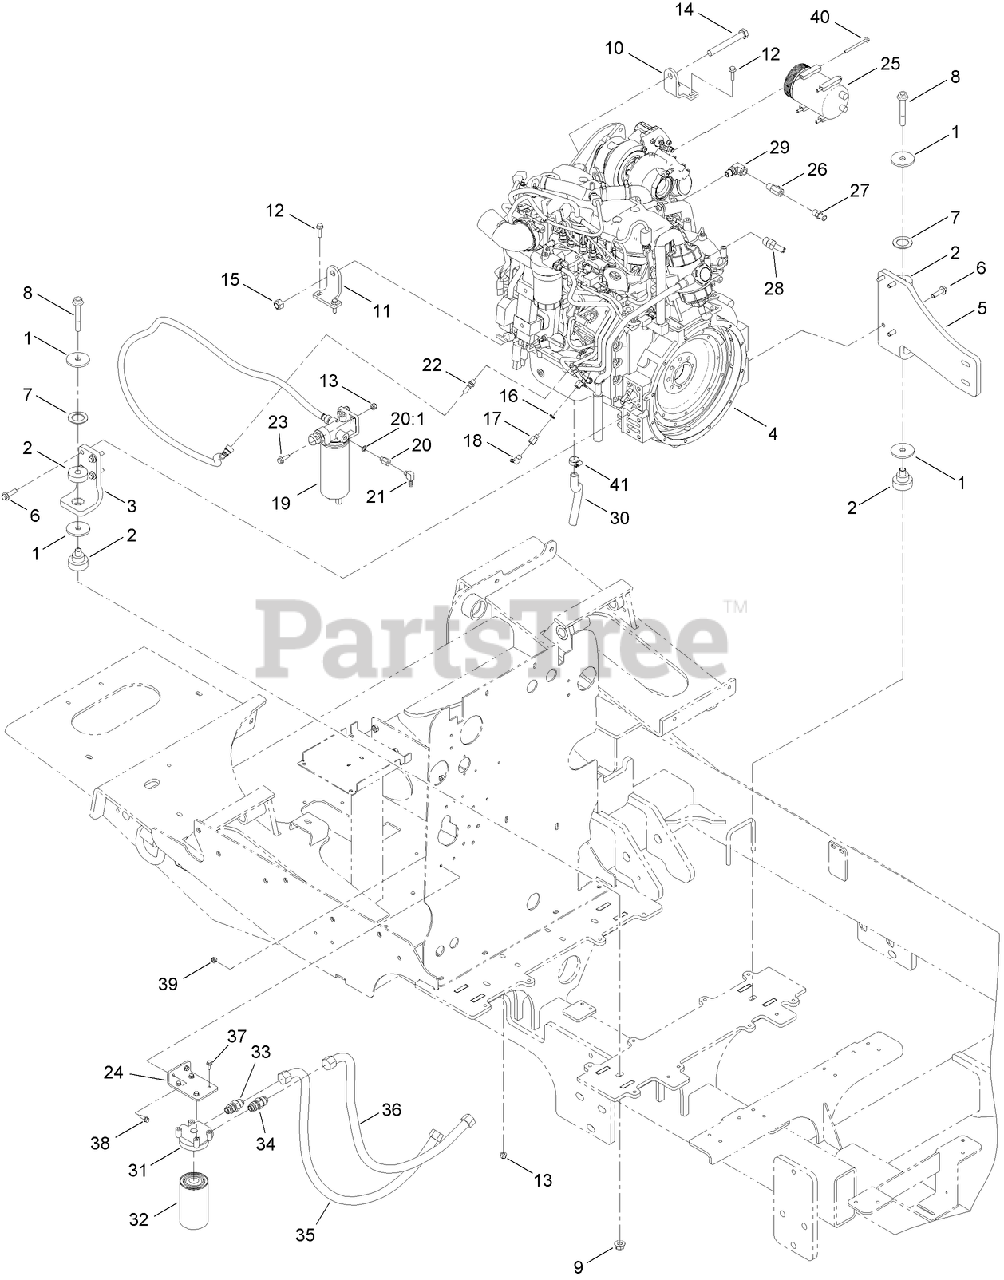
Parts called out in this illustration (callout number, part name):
1	WASHER
2	ISOLATOR-MOUNT, UNIVERSAL
3	MOUNT-ENGINE, FRONT (RH)
5	MOUNT-ENGINE, FRONT (LH)
6	SCREW-HHF
7	SPACER-ISOLATOR
8	SCREW-FLANGE
9	NUT-HHF
10	MOUNT-ENGINE
11	MOUNT-ENGINE
12	SCREW-HHF
13	NUT-LOCK, NI
14	SCREW-HH
15	NUT-LOCK
16	SEAL-FITTING, FUEL
17	FITTING-REDUCER
18	FITTING-ELBOW, 90
19	FUEL FILTER ASM
20	FITTING-REDUCER
20:1	SEAL-FITTING, FUEL
21	FITTING-ELBOW, 90
22	FITTING-FUEL
23	SCREW-HHF
24	PLATE-MOUNTING, FILTER
25	COMPRESSOR-A/C
26	VALVE-BALL
27	FITTING-STRAIGHT
28	FITTING-ELBOW, 45
29	FITTING-ELBOW, 90
30	HOSE-DRAIN, OIL
31	HEAD-FILTER, OIL
32	FILTER-OIL
33	FITTING-OIL
34	FITTING-OIL
35	HOSE-OIL
36	HOSE-OIL
37	SCREW-HHF
38	SCREW-HHF
39	NUT-LOCK, HHF
40	SCREW-HHF
41	CLAMP-HOSE
